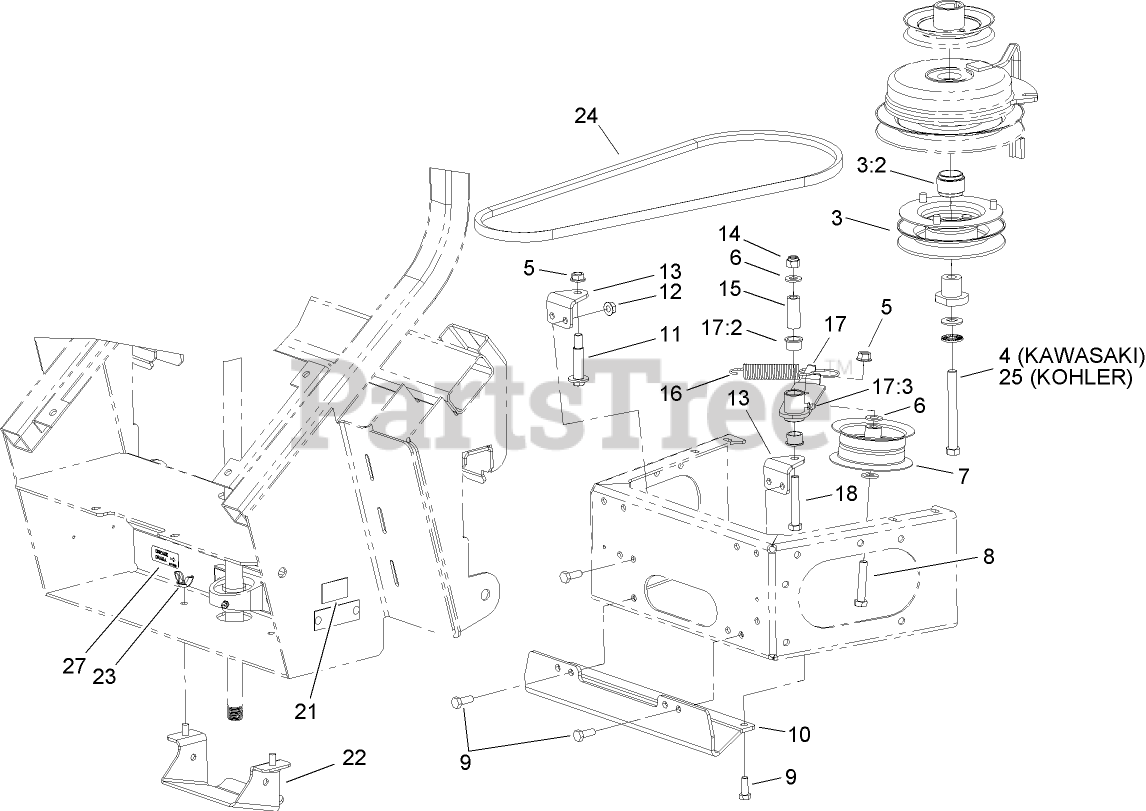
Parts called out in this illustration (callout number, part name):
3	PULLEY ASM
3:2	Spacer-Pulley
4	SCREW-HH
5	NUT-HF
6	WASHER-FLAT
7	PULLEY-IDLER, FLAT
8	SCREW-HH
9	SCREW-HH
11	SCREW-SHOULDER, HWH
12	NUT-HF
13	Bracket-Mount, Idler
14	NUT-LOCK, NI
15	BUSHING
16	Spring-Extension
17	IDLER ARM ASM
17:2	BUSHING
17:3	FITTING-GREASE
18	SCREW-HH
21	Decal-Conversion, Ce
22	Pulley Guard ASM
23	NUT-WING
24	V-BELT
25	SCREW-HH
27	Decal-Grease
